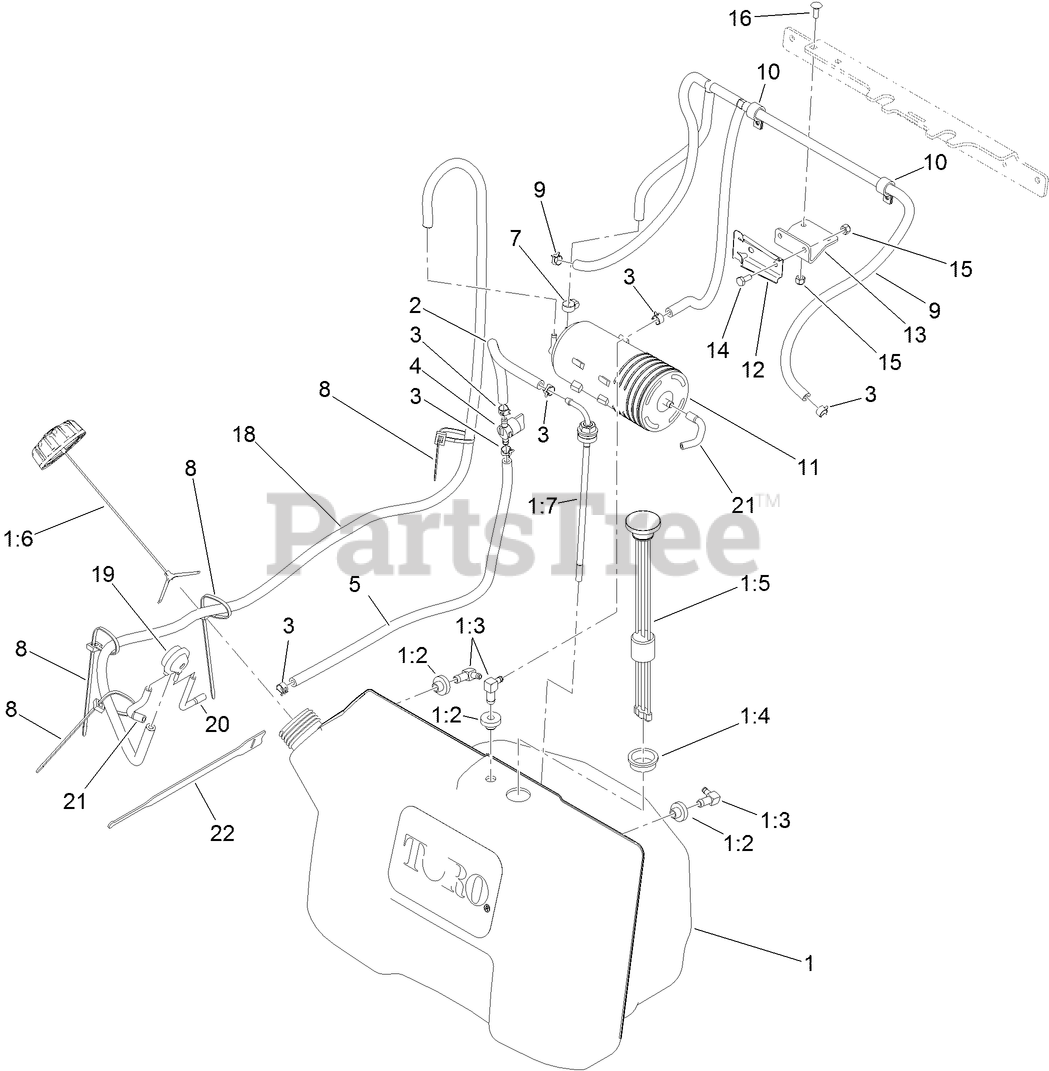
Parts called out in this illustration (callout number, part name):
1	TANK ASM
1:2	BUSHING
1:3	ELBOW-90 DEG
1:4	GROMMET
1:5	GUAGE-FUEL
1:6	CAP-FUEL, RATCHETING
1:7	FITTING-FUEL, BULKHEAD
2	HOSE-FUEL
3	CLAMP-HOSE
4	VALVE-FUEL
5	HOSE-FUEL
7	CLAMP-WORM
8	TIE-CABLE
9	VENT HOSE ASM
10	CLAMP-CABLE
11	CANISTER-CARBON, 800CC
12	BRACKET-CANISTER, CARBON
13	BRACKET-CANISTER
14	SCREW-HH
15	NUT-LOCK, NI
16	BOLT-CARR
18	HOSE-FUEL
19	VALVE-CONTROL, VACUUM
20	HOSE-VENT, FORMED
21	HOSE-VENT, FORMED
22	STRAP-VELCRO, CABLE TIE
